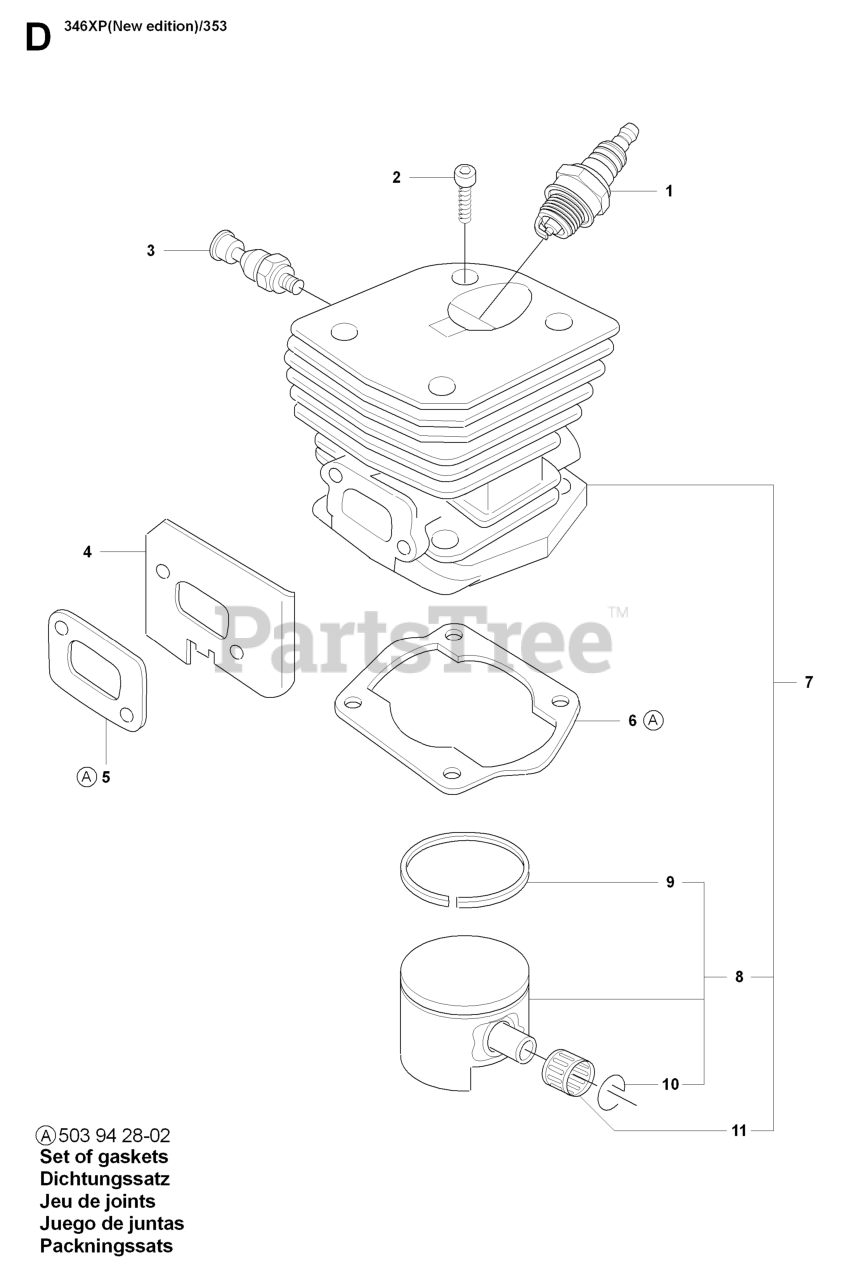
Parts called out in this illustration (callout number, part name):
1	SPARK PLUG RCJ7Y
2	SCREW MC6S 5X25
3	DECOMPRESSION VALVE
7	CYLINDER
7	CYLINDER ASSY
7	%CYLINDER
8	PISTON
8	%PISTON
8	PISTON ASSY
9	PISTON RING
9	%PISTON RING
10	LOCKING RING
11	SUPPORT BUSHING
A	GASKET SET
